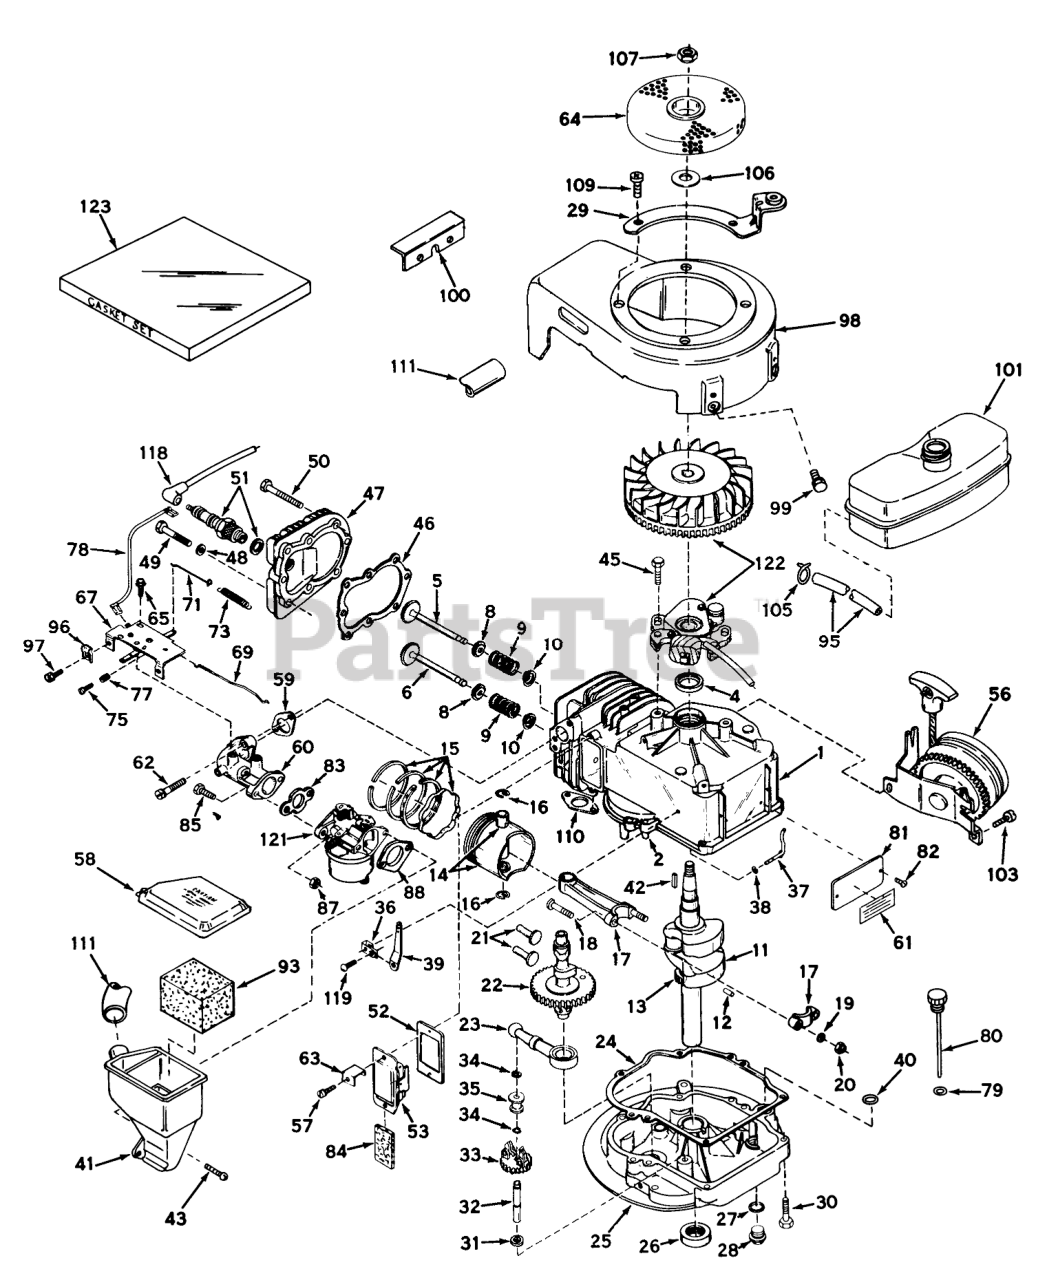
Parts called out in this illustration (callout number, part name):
1	Cyl. Assy. (Incl. Nos. 2 & 4)
2	Pin-Dowel
4	OIL SEAL
5	Valve, Intake (Std.) (Incl. Nos. 8, 9 & 10)
5	Valve, Intake (1/32" Oversize) (Incl. Nos.8, 9 & 10)
6	Valve, Exhaust (Std. ) (Incl. Nos. 8, 9 & 10)
6	Valve, Exhaust (1/32" Oversize) (Incl. Nos.8, 9 & 10)
8	Cap-Upper Valve Spring
9	Spring-Valve
10	Cap-Valve, Spring
11	Crankshaft Assy. (Incl. Nos.12 & 13)
12	Pin, Groove
13	Gear, Crankshaft
14	Piston & Pin Assy. (Incl. 2 of No. 16) (Std.)
14	Piston & Pin Assy. (Incl.2 of No. 16) (.010 Oversize)
14	Piston & Pin Assy. (Incl. 2 of No. 16) (.020 Oversize)
15	Piston Ring Set Std.
15	Piston Ring Set .010 O.S.
15	Piston Ring Set .020 O.S.
16	Ring-Retaining, Piston Pin
17	Rod Assy., Connecting (Incl. Nos. 18, 19 & 20)
18	Bolt, Connecting
20	LOCKNUT
21	Lifter-Valve
22	Camshaft
23	Oil Pump ASM
24	Gasket, Mounting
25	Flange Assy., Mtg. (Incl. Nos 26, 27, 28 & 32)
26	Seal Oil
27	Gasket-Oil Drain
28	Plug Oil Drain
29	Bracket Assy., Starter
30	Screw (1/4-20 x 1-1/4)
31	Washer-Flat
32	Shaft-Governor
33	Governor Gear ASM
34	Ring-Retaining
35	Spool-Governor
36	Clamp-Lever, Governor
37	Rod, Governor (Incl. No .38)
38	Washer-Flat
39	Governor Lever
41	Body, Air Cleaner
42	Key Flywheel
43	Screw, Fil. Hd. Sems
46	Gasket-Cylinder Head
47	CYLINDER HEAD
49	Screw
50	Screw Hex Hd. Cap
51	SPARK PLUG
52	Gasket Breather
53	Breath. Assy. (Incl. Nos.52 & 84)
56	Starter, Side Mount
58	Cover, Air Cleaner
59	Gasket, Intake
60	Pipe, Intake
61	480B GIL SNWTHWR O/
62	Screw, Fil. Hd. Sems
63	Retainer Clip
64	Screen, Flywheel
65	Screw (10-24 x 9/16)
67	Control Assy., Speed
69	Link, Throttle to Governor
71	Link-Governor
73	Spring, Governor
75	Screw
77	Spring-Compression
78	Wire, Ground
80	Dipstick, Oil
81	IDENTIFICATION PLATE
84	Element-Breather
85	Screw (1/4-28 x 7/8)
87	Nut and Lock Washer (1/4-28)
88	Gasket-Air Cleaner
93	Element, Air Cleaner
95	Line-Fuel (8.62)
96	Conduit
97	Screw (10-32 x 3/8)
98	Housing, Blower
99	Screw (1/4-20x19/32)
100	Bracket, Shroud
101	Tank, Fuel
103	Screw
105	Clamp-Line, Fuel
106	Washer
107	Hex Nut
110	Gasket Exhaust
111	Tube, Air Cleaner
118	Cover-Spark Plug
119	Screw
121	Carburetor
122	Magneto
123	Gasket Set
